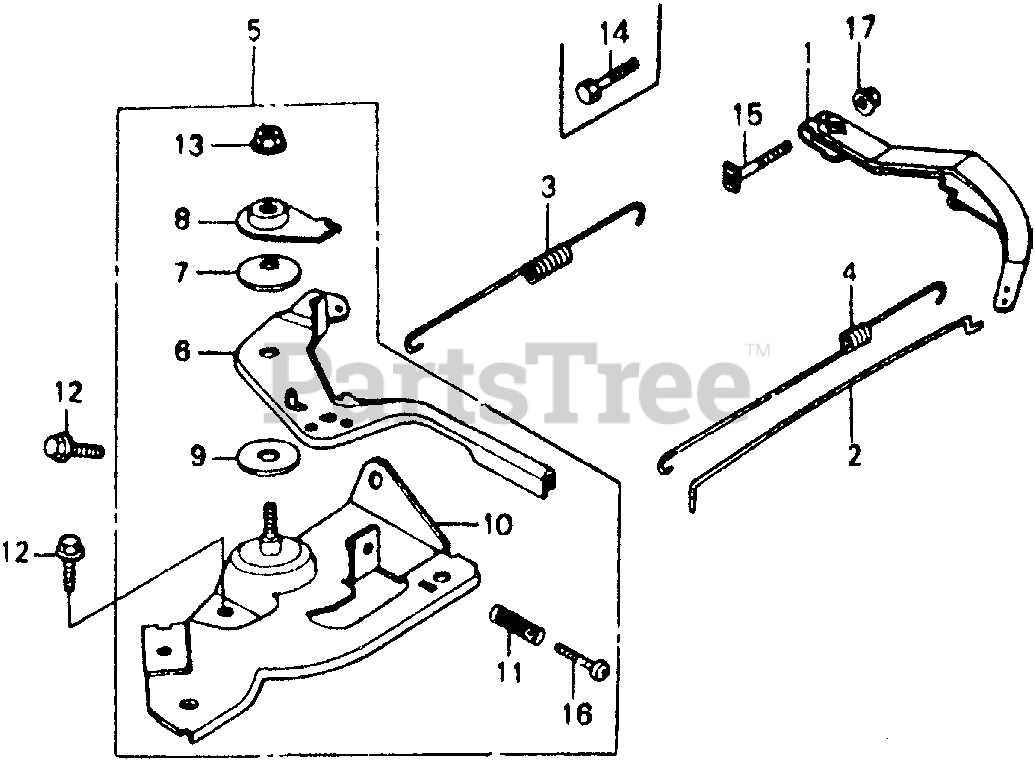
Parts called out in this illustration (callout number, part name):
1	ARM, GOVERNOR
2	ROD, GOVERNOR
3	SPRING, GOVERNOR
4	SPRING, THROTTLE RETURN
5	CONTROL ASSY.
6	LEVER, CONTROL
7	SPRING, LEVER
8	WASHER, CONTROL LEVER
9	SPACER, CONTROL LEVER
10	BASE, CONTROL
11	SPRING, CONTROL ADJUSTING
12	BOLT, FLANGE (6X12) (CT200)
13	NUT, SELF-LOCK (6MM)
14	BOLT, HEX. (6X20)
15	BOLT, GOVERNOR ARM
16	SCREW, PAN (5X20)
17	NUT, FLANGE (6MM)
